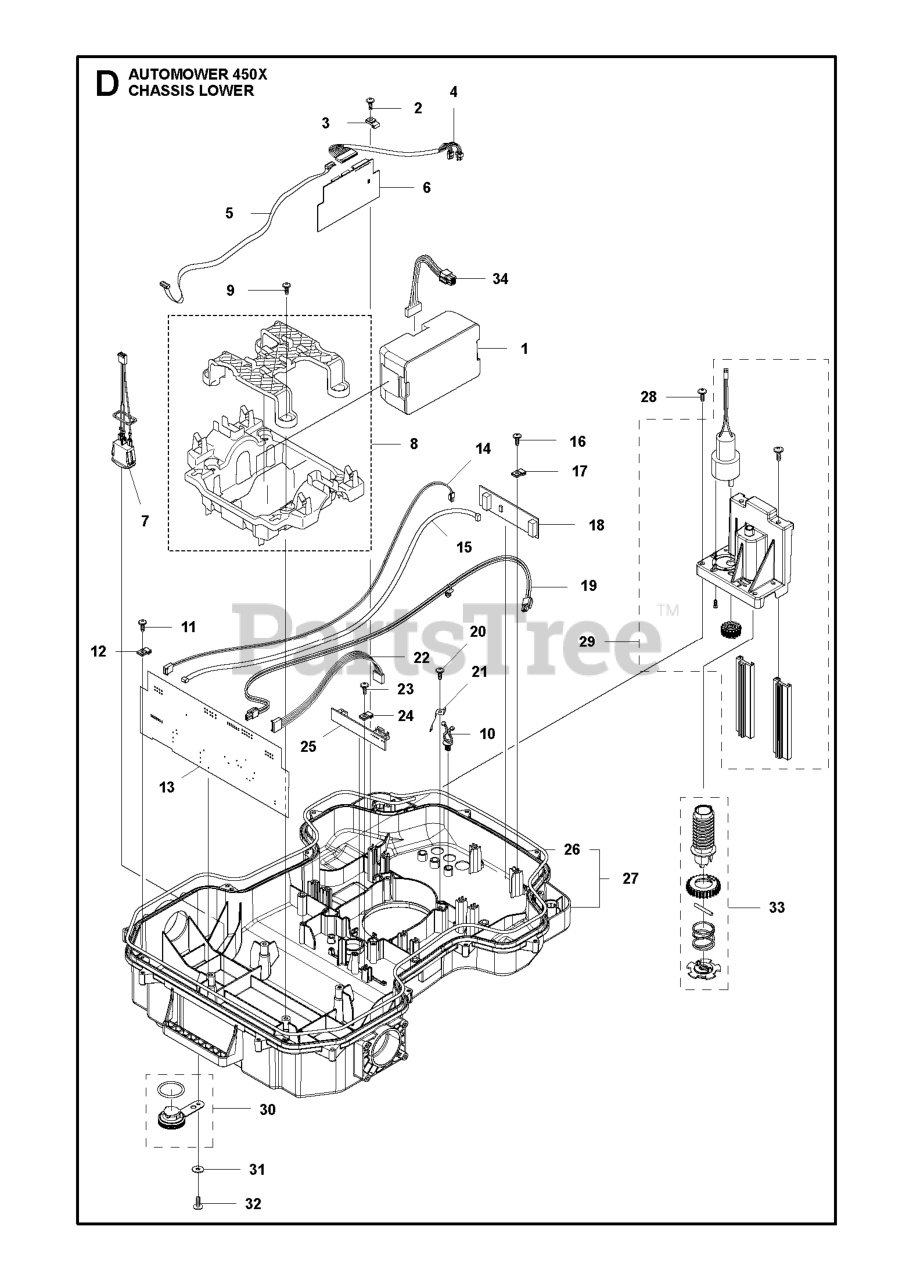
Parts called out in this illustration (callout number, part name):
1	BATTERY
2	SCREW 14MM
3	CLAMP PCB
4	LOOM ULTRA SONIC EXTENSION
5	LOOM AUX
6	PRINTED CIRCUIT ASSY ULTRASONI
7	LOOM ON/ OFF
8	HOLDER KIT BATTERY
9	SCREW ITXPANT
10	HOLDER TWIST LOCK
11	SCREW 14MM
12	CLAMP PCB
13	PRINTED CIRCUIT ASSY PCBA MAIN
14	WIRING ASSY LED LIGHT EXTENSIO
15	LOOM LOOP SENSOR
16	SCREW 14MM
17	CLAMP PCB
18	PRINTED CIRCUIT ASSY LOOP SENS
19	LOOM CHARGING LINK HIGH CHARGI
20	SCREW 14MM
21	SPRING GUIDE HEIGHT ADJUSTMENT
22	LOOM HEIGHT ADJUSTMENT
23	SCREW 14MM
24	CLAMP PCB
25	PRINTED CIRCUIT ASSY PCBA CUTT
26	SEALING STRIP
27	CHASSIS KIT LOWER
28	SCREW 14MM
29	MOTOR ASSY HEIGHT MOTOR
30	PLUG KIT
31	WASHER
32	SCREW ITXPANT
33	SCREW KIT
34	WIRING ASSY BATTERY CABLE
